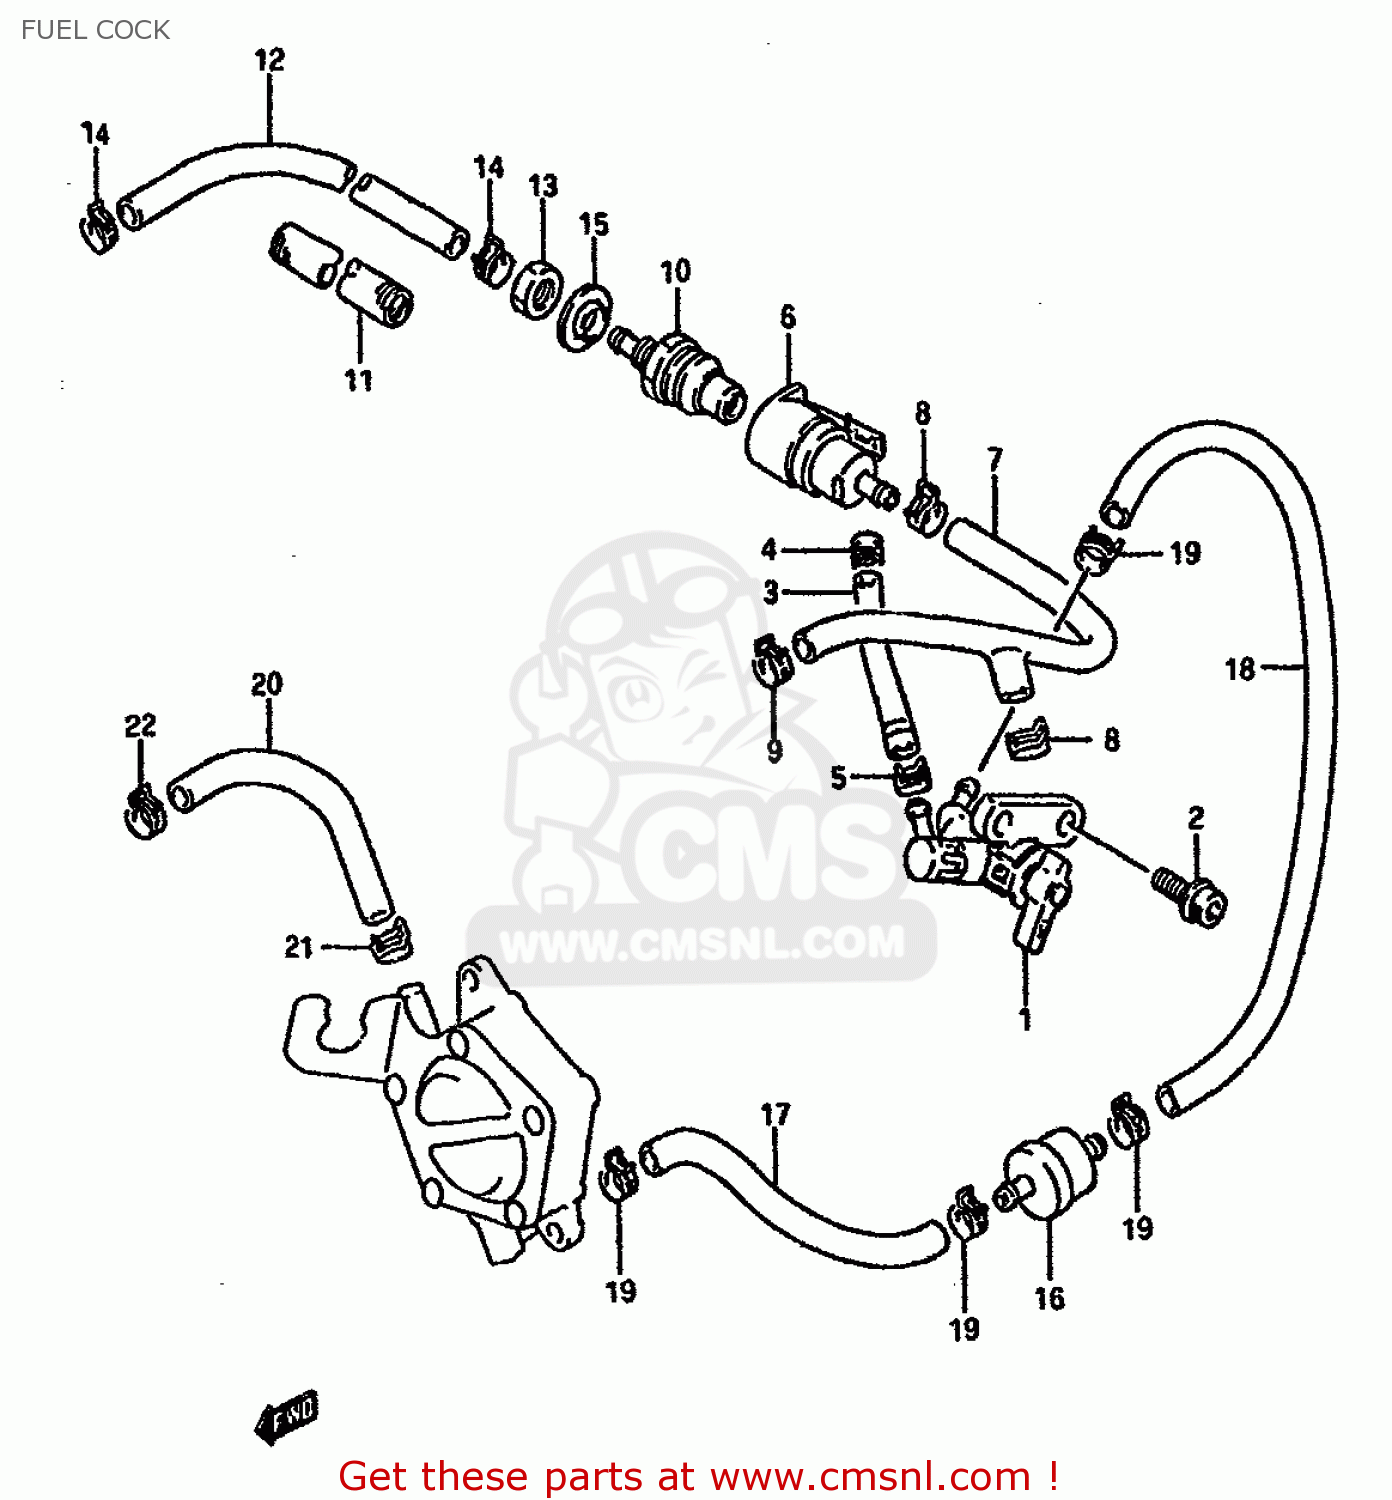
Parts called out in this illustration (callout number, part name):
1	COCK ASSY, FUEL
2	BOLT
3	HOSE,FUEL ON
4	CLIP
5	CLIP
6	SOCKET,FUEL HOSE LH
7	HOSE,FUEL 3WAY
8	CLIP
9	CLIP
10	PLUG
11	HEATSHIELD,FUEL HOSE
12	HOSE,FUEL JOINT,R
13	NUT
14	CLIP
15	WASHER
16	FILTER,FUEL
17	HOSE,FUEL FILTER & PUMP
18	HOSE
19	CLIP
20	HOSE,PUMP & CARB
21	CLIP
22	CLIP
